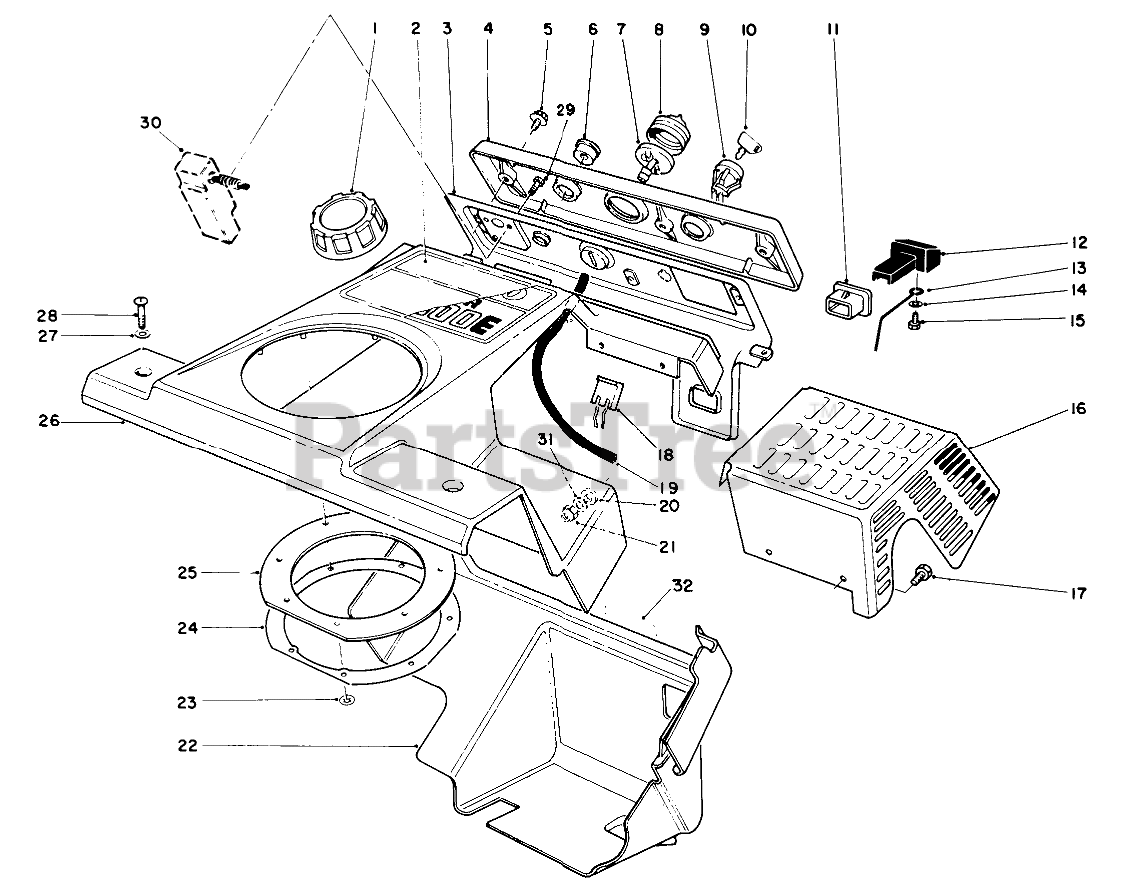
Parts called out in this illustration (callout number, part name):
1	CAP-FUEL ASM
2	Decal-CCR-2000 Electric Start
3	Panel-Control (Incl. Ref. #6-8 & 11)
4	Plate-Name
4	PLATE
5	SCREW
6	GUIDE-ROPE, STARTER
7	BODY-PRIMER
8	Bulb Primer
9	SWITCH
10	KEY-IGNITION
11	FITTING
12	CONTROL-CHOKE
12	CHOKE CONTROL
13	Linkage-Choke
14	Washer
15	#8 X .625" PHILPS PAN H
16	Wa-Shield
17	SCREW-SHH
18	CONNECTOR-BODY
19	PRIMER HOSE
20	WASHER
21	NUT-LOCK, SIDE
22	LOWER SHROUD
23	PALNUT
24	Retainer-Chute Seal
25	SEAL-CHUTE
26	Upper Shroud Assembly (Incl. Ref. #2 & 23-25)
27	WASHER-FLAT
28	SCREW-PPH
29	SCREW-PLASTITE
30	Switch Assembly
31	WASHER-FLAT
32	DECAL
